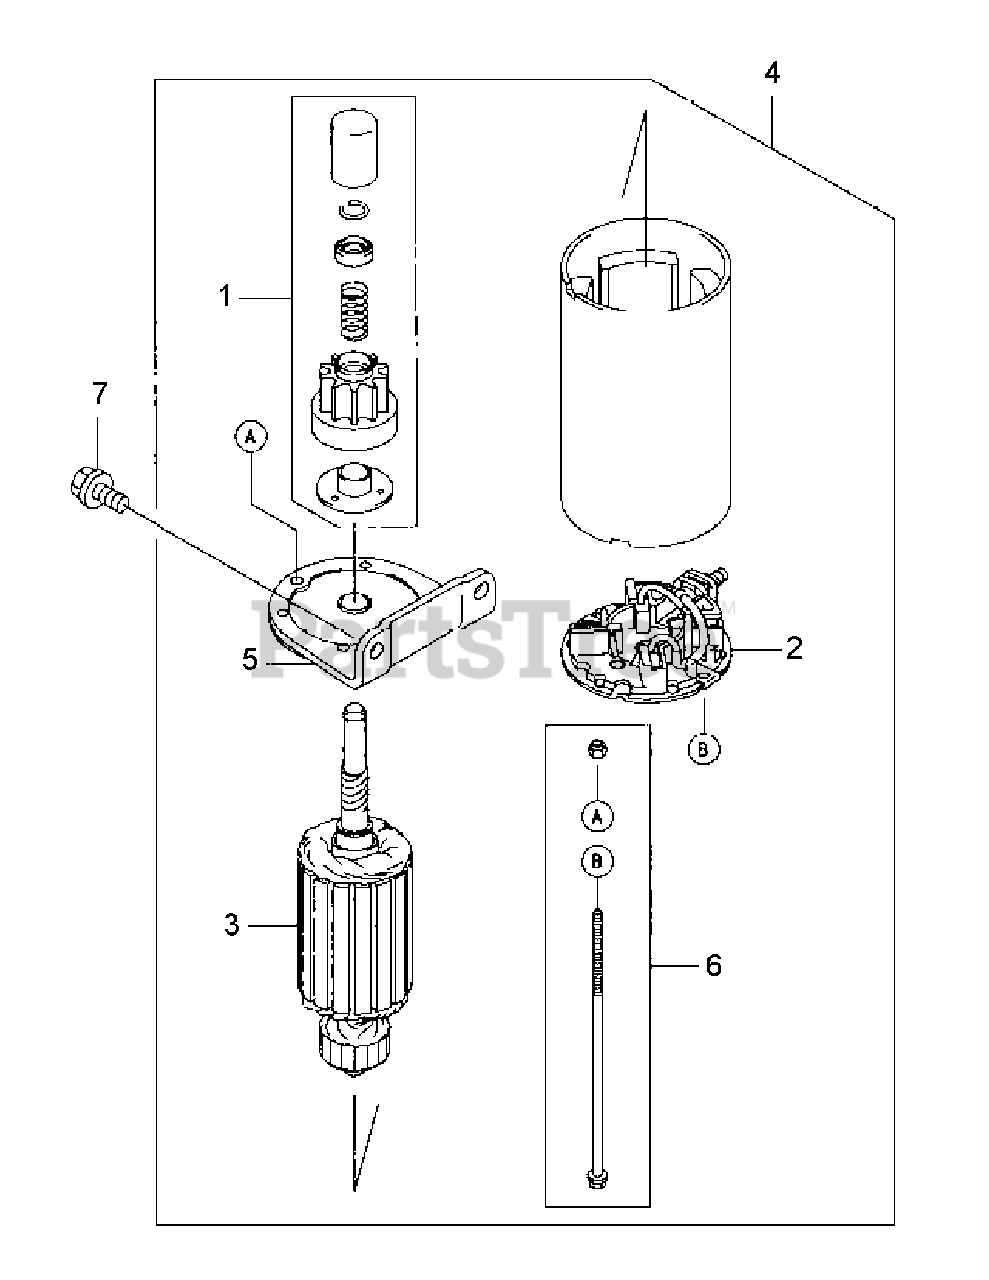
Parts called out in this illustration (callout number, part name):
1	GEAR ASSY.
4	ELECTRIC STARTER
5	BRACKET ASSY.
7	FLANGED BOLT
